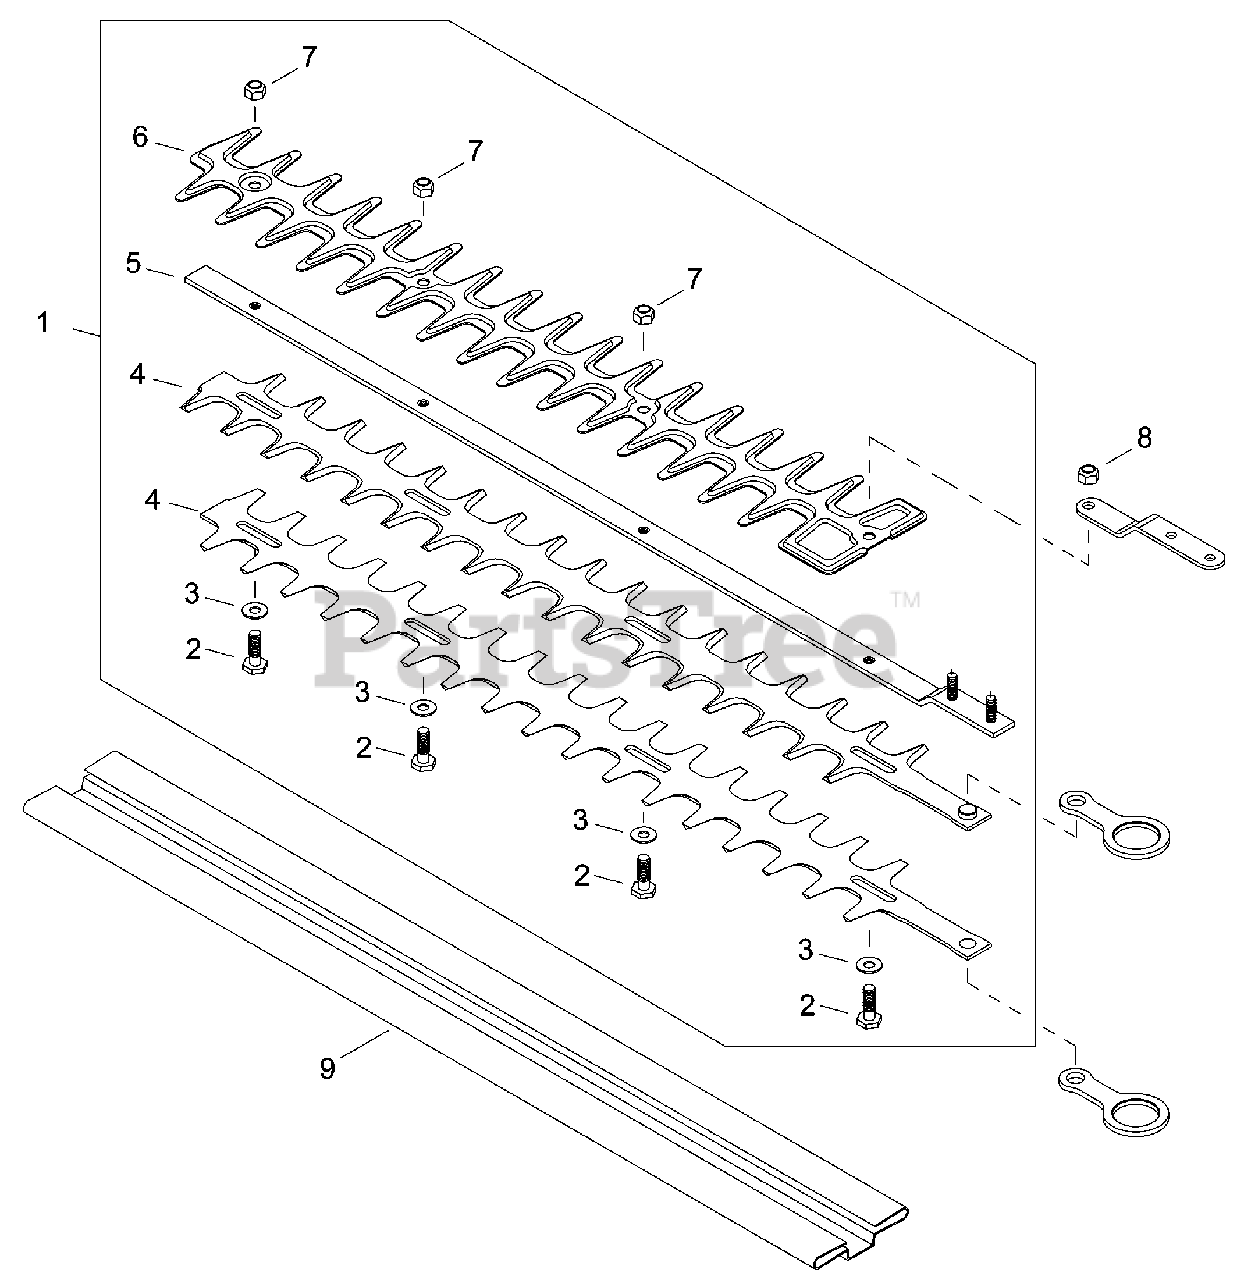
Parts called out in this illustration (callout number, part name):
1	CUTTER ASSY, 22" CHROME
2	BOLT M6×20
3	WASHER M6
4	CUTTER, CHROME 22"
5	GUIDE BAR 22"
6	GUARD, CUTTER BLADE
7	NUT, LOCK M6
8	NUT, LOCK M6
9	SCABBARD
